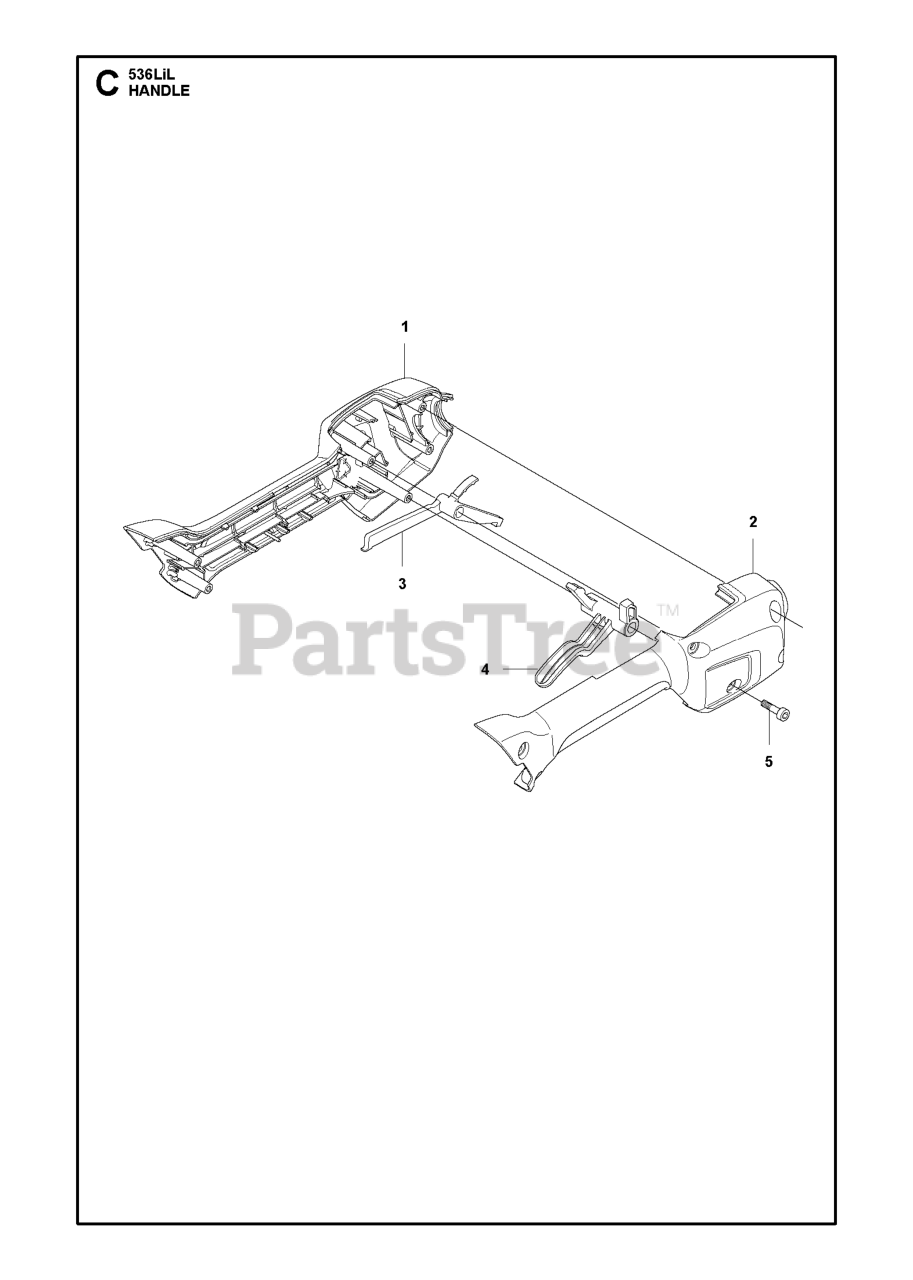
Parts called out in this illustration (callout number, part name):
1	HANDLE HALF LEFT
2	HANDLE HALF RIGHT
3	THROTTLE LOCKOUT
4	TRIGGER
5	SCREW
